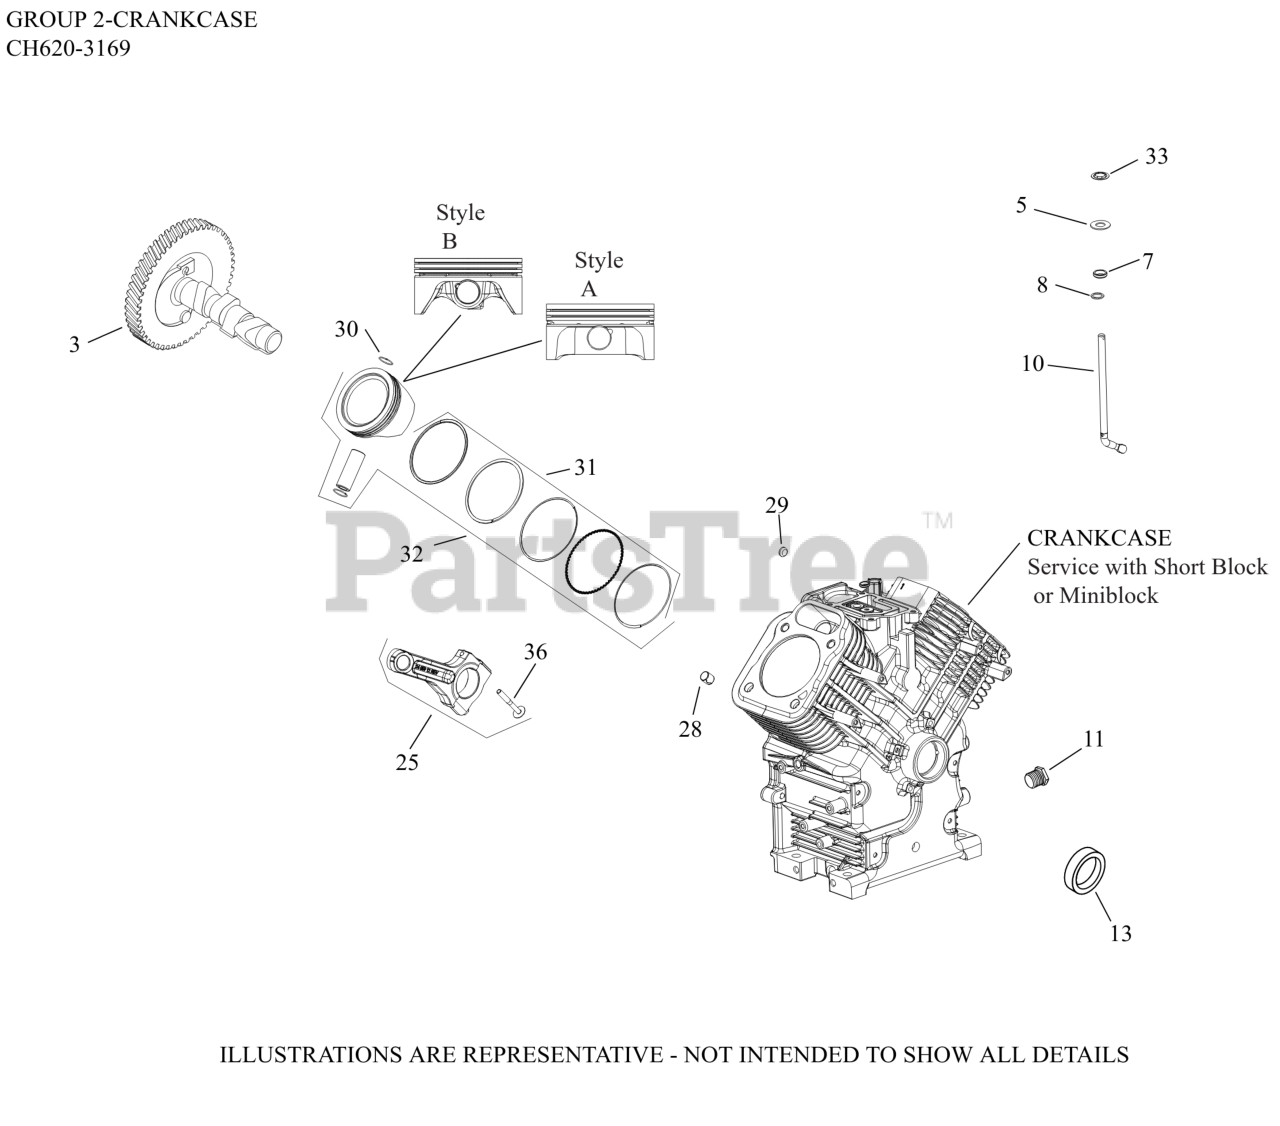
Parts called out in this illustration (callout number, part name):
3	KIT, CAMSHAFT
5	WASHER, FLAT 9 MM
7	SEAL, GOVERNOR CROSS SHAFT
8	WASHER, FLAT 11/32"
10	SHAFT, GOVERNOR CROSS
11	PLUG, HD PIPE 3/8"
13	SEAL, OIL (HELIX LIP)
25	ROD, ASSEMBLY CONNECTING
28	PIN, LOCATING
29	PLUG, CUP
30	RETAINER, PISTON PIN
31	RING SET (STD) STYLE B
31	RING SET (.08) STYLE B
31	RING SET (.25) STYLE B
31	RING SET (.50) STYLE B
32	KIT, PISTON (STD) STYLE B
32	KIT, PISTON (.08) STYLE B-(#DSC)
32	KIT, PISTON (.25) STYLE B
32	KIT, PISTON (.50) STYLE B
33	RETAINER, RING
36	KIT, ROD BOLTS-(#25086677S)
